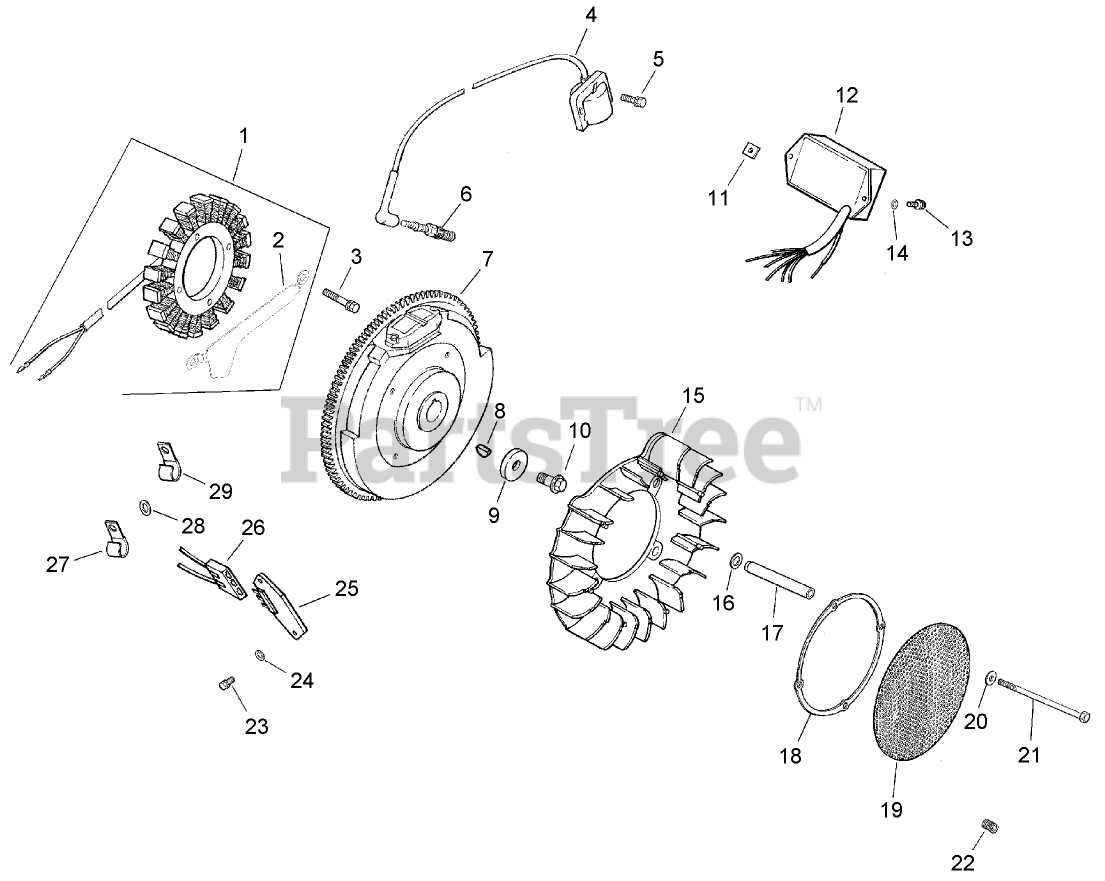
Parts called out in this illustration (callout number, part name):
1	15 Amp Stator Kit (Includes 2)
2	Bracket-Wire, Stator
3	SCREW-THREAD FORMING (M5X0.8X25)
4	Module-Ignition
5	Screw-Socket, Hex (M5x0.8x25)
6	Spark Plug
7	Flywheel
8	KEY (3/16 X 5/8)
9	WASHER-FLAT (13/32)
10	SCREW-FLANGE (M10X1.5X45)
11	NUT-PLASTIC
12	Module-Advance, Speed
13	SCREW-PPH (11-16X1/2)
14	Washer-Lock, Internal Tooth (1/4)
15	Fan
16	Washer-Spring (10MM)
17	Spacer
18	Ring-Support
19	Screen-Grass
20	WASHER-FLAT (1/4)
21	Screw-Socket Truss Head, Cap
22	Screw-Set (10-24X.25)
23	SCREW-PHL HD (11-16X.88)
24	WASHER-FLAT (.188)
25	Rectifier-Regulator, 15 amp
26	Connector (3 contact)
27	CLIP-CABLE
28	WASHER-FLAT (1/4)
29	Clip-Cable
